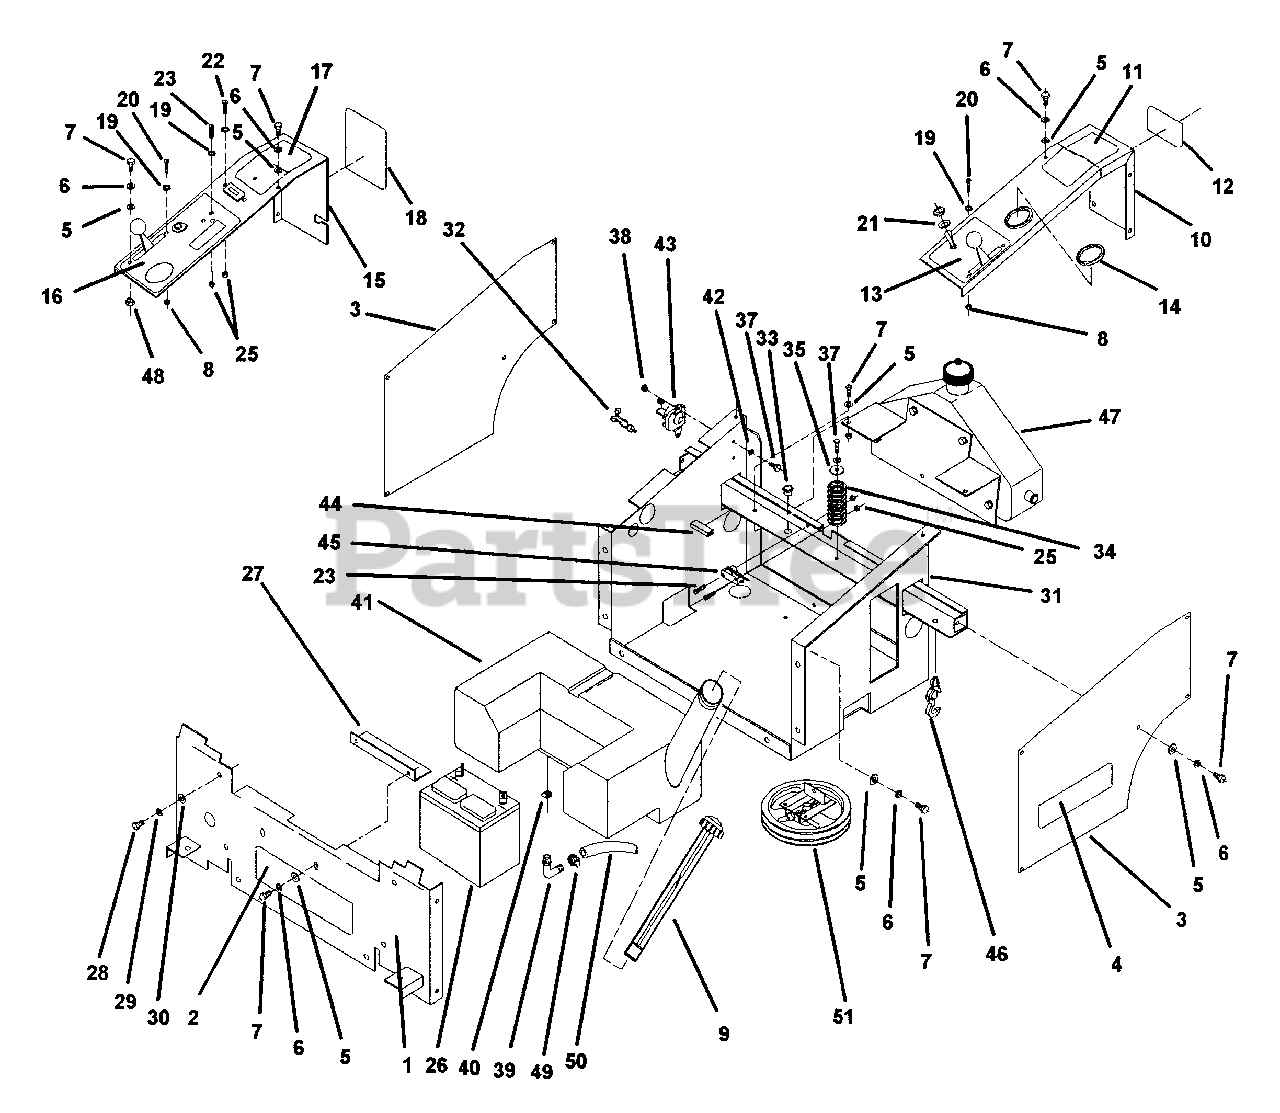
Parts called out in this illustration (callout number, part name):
1	SEAT SUPPORT FRONT ASSEMBLY (W/DECALS)
2	DECAL, SNAPPER
3	FENDER SKIRT
4	DECAL, I.D. "ZU2014K"
5	WASHER, FLAT STD. 5/16"
6	LOCK WASHER, 5/16" HEAVY SPRING
7	BOLT, 5/16-18 X 3/4" GR. 5
8	LOCKNUT, #8-32 NYLOC
9	FUEL GAUGE CAP
10	FENDER CAP (w/ decals) L.H.
11	DECAL, CAUTION
12	DECAL, TOWING WARNING
13	DECAL, BLADE/CHOKE
14	TRIM, U-CHANNEL GAS TANK
15	FENDER CAP (w/decals, less #62391) R.H.
16	DECAL, INSTRUMENT PANEL
17	DECAL, CAUTION
18	DECAL, BELT TENSIONING
19	WASHER, #8 FLAT
20	SCREW, MACHINE, #8-32 X 1/2"
21	D-WASHER
22	SCREW, MACHINE, #6-32 X 5/8"
23	SCREW, MACHINE, #6-32 X 1"
25	LOCKNUT, #6-32 NYLOC
26	BATTERY 12 VOLT
27	BATTERY CLAMP ANGLE
28	BOLT, 3/8-16 X 3/4" GR. 5
29	LOCK WASHER, 3/8" HEAVY SPRING
30	WASHER, FLAT STD. 3/8"
31	SEAT SUPPORT WELDMENT
32	BLIND HOLE KURLY
33	BUSHING, PLASTIC
34	SEAT SPRING
37	BOLT, 1/4-20 X 3/4" GR. 5
38	LOCKNUT, 1/4--20 NYLOC
39	ELBOW, 90D 1/4 NPT X 1/4 BARB
40	CLAMP, .31 MIN. X 1.87 MAX. HOSE DIA.
41	FUEL TANK
42	WASHER FLAT STD. 1/4"
43	SOLENOID, 12V STARTER
44	EDGE GUARD
45	SWITCH, ENCL, SPDT 15A HINGED LEVER
46	FITTING 1/2" ROSE BUD CLIP
47	OIL TANK ASSEMBLY
48	NUT, HEX. 5/16-18 NYLOC
49	CLAMP, HOSE 1/2 ",STAINLESS
50	HOSE, FUEL 1/4 ID X 1/2 OD
51	DOUBLE GROOVE IDLER ASSEMBLY
